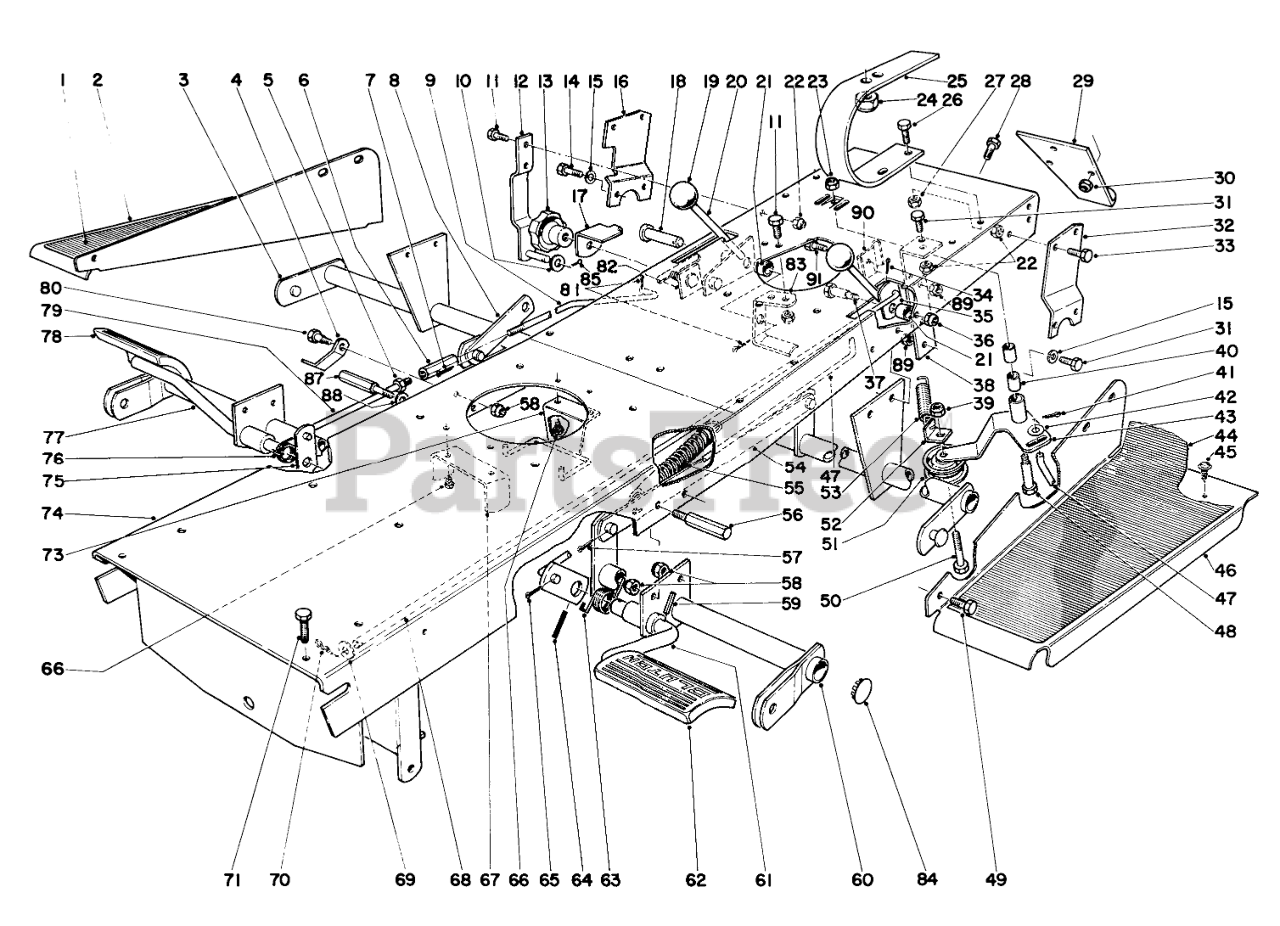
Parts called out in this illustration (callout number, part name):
1	Pad R. H.
2	Footrest R.H.
3	Cross Tube
4	Pedal Latch
5	NUT-JAM
6	Screw Brake Adjusting
7	PIN-COTTER
8	Lift Link
9	Brake Rod Rear
10	WASHER-FLAT
11	SCREW-HH
12	Brake Hanger
14	SCREW-HH
15	WASHER-LOCK
16	Support R.H.
17	Slide
20	Lever
21	Spacer
22	Nut
25	Seat Spring
26	SCREW-HH
28	SCREW-HH
29	Hitch
31	SCREW-HH
32	Support Left
33	SCREW-HH
34	PIN-COTTER
35	Lever
37	Shoulder Bolt
38	Support Transaxle
40	Bushing
41	PIN-COTTER
42	WASHER-PLAIN
43	Idler Arm (Incl. Ref. #40)
44	Pad Left
45	10-16 X 3/8 THDG SCREW
46	Footrest
47	Clutch Rod
48	Shoulder Bolt
49	SCREW-HH
50	SCREW-HH
51	Idler Pulley
53	Tension Spring
54	Lift Equalizer
55	Spring Counterbalance
56	Pedal Stop
57	PIN-COTTER
58	Nut
59	PIN-SPRING
60	Cross Tube Front
61	Pedal L.H.
62	CLUTCH PAD
63	Pedal Return Spring
64	RollPin
65	PIN-COTTER
66	10-32 X 1/2 PHILLIPS
67	Cutter Guide
68	Rod Clutch
69	WASHER-FLAT
70	PIN-COTTER
71	He Ha. Screw
73	Belt Traction Guide
74	Frame
75	Lever Pedal Shaft
76	Pedal Return Spring
77	Pedal R.H.
78	PAD-BRAKE
79	Brake Rod Front
80	Shoulder Bolt
81	PIN-COTTER
82	Knob Plate
83	Support Guide
84	Plug Button
85	PIN-COTTER
87	Brake Stop
88	Washer
89	NUT-LOCK, CONE
90	Belt Guide
91	SCREW-HH
